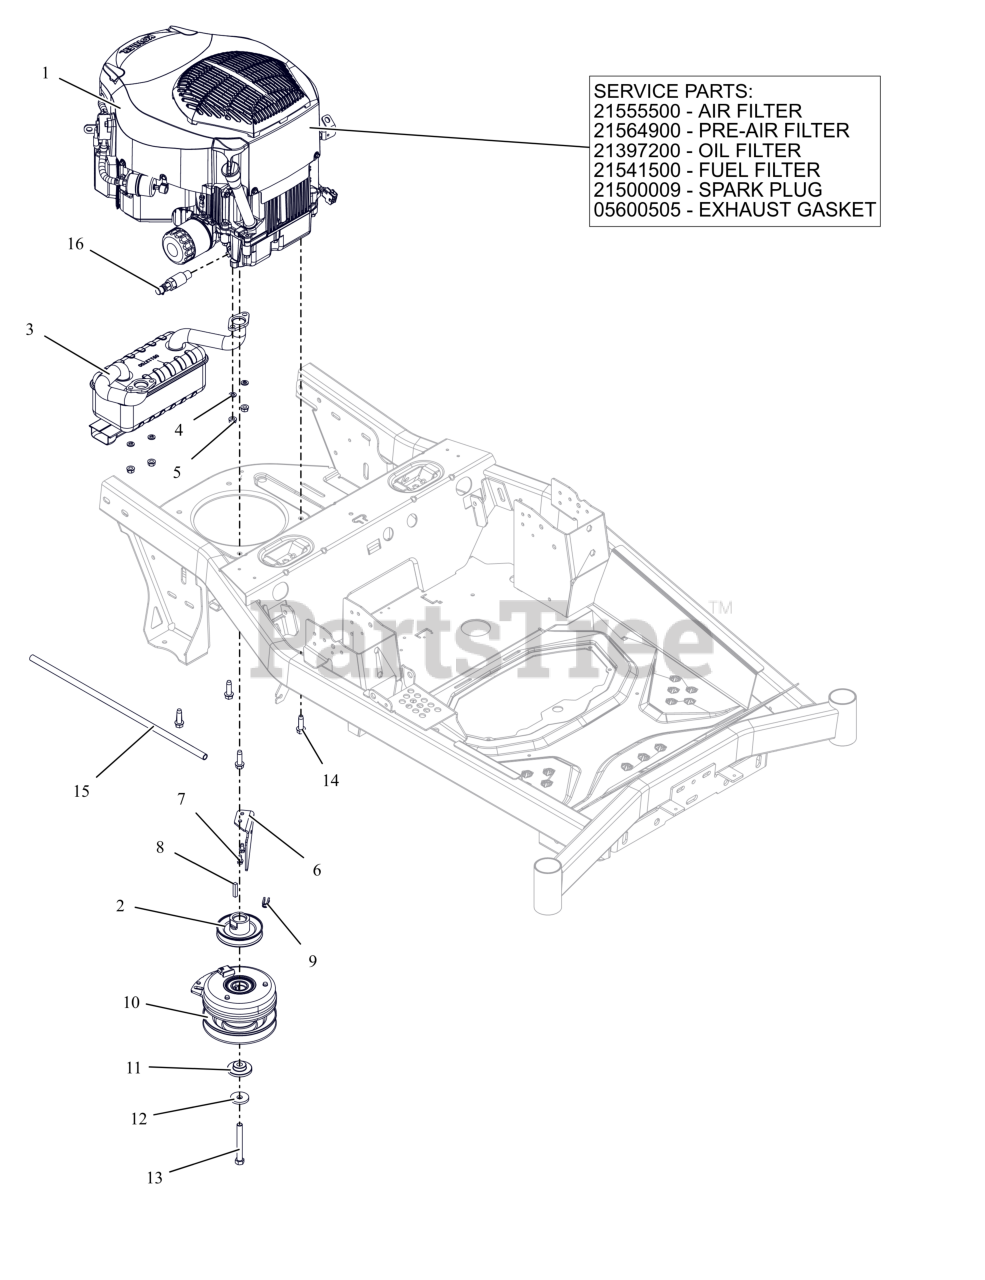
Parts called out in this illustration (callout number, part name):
1	ENGINE, KOHLER - KT730
1	AIR CLEANER, KOHLER
1	PRE-CLEANER, KOHLER
1	FILTER, OIL - KOH CV20
1	FILTER, FUEL
1	PLUG, SPARK KOHLER
1	GASKET, MUFFLER KOHLER TWIN
2	WLDMT-PULLEY-4.831OD X1.003
3	MUFFLER, KOHLER
4	WSHR,LK-REG .312X.078 ZCC
5	NUT-LK-TOP-FLG .312-18 GF ZCC
6	BRKT- CLUTCH STOP
7	SCR-TAP .25-20X.50 HWH ZCC
8	KEY-SQ .25 X 1.25 X .25 SAE
9	BSHG, CLUTCH
10	CLUTCH, WARNER-IXR-18211
11	BSHG-FLG .469X1.06X.574X2.0
12	WASHER, 7/16" SPRING DISK
13	BLT- HEX .44-20X3.50 G8 ZCC NT
14	SCR,TAP .375-16X1.25HWH TR ZCC
15	HOSE- OIL DRAIN
16	DRAIN, OIL
